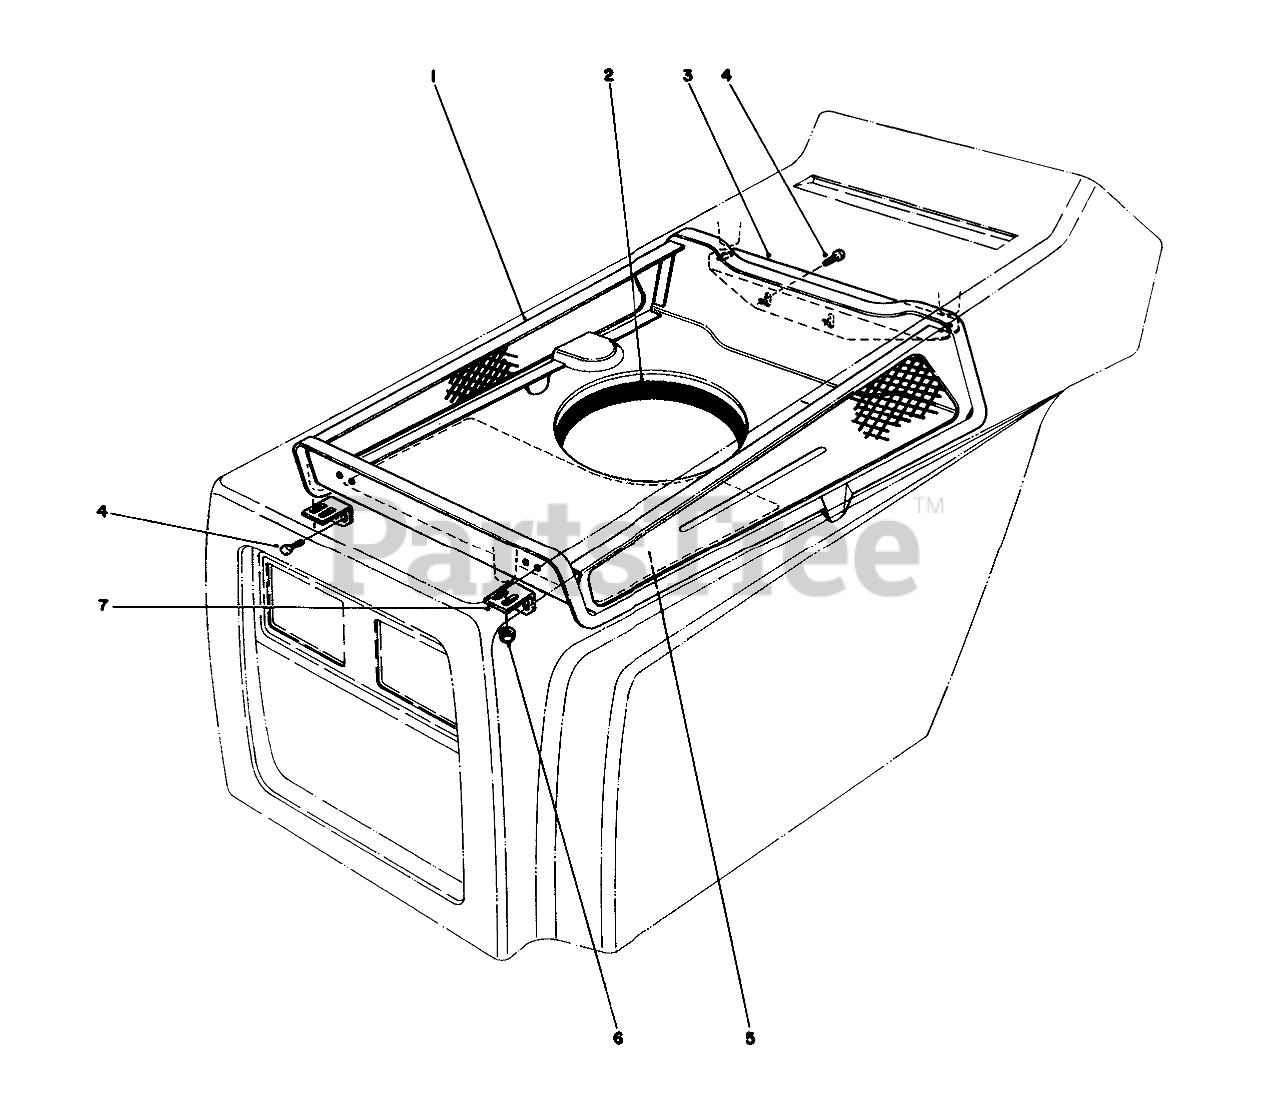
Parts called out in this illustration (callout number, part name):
1	Duct Hood
2	Seal Engine
3	Bracket Rear Duct Support
4	SCREW-HWHTF
5	Decal Service
6	NUT-LOCK, NI
7	Bracket Front Duct Support
